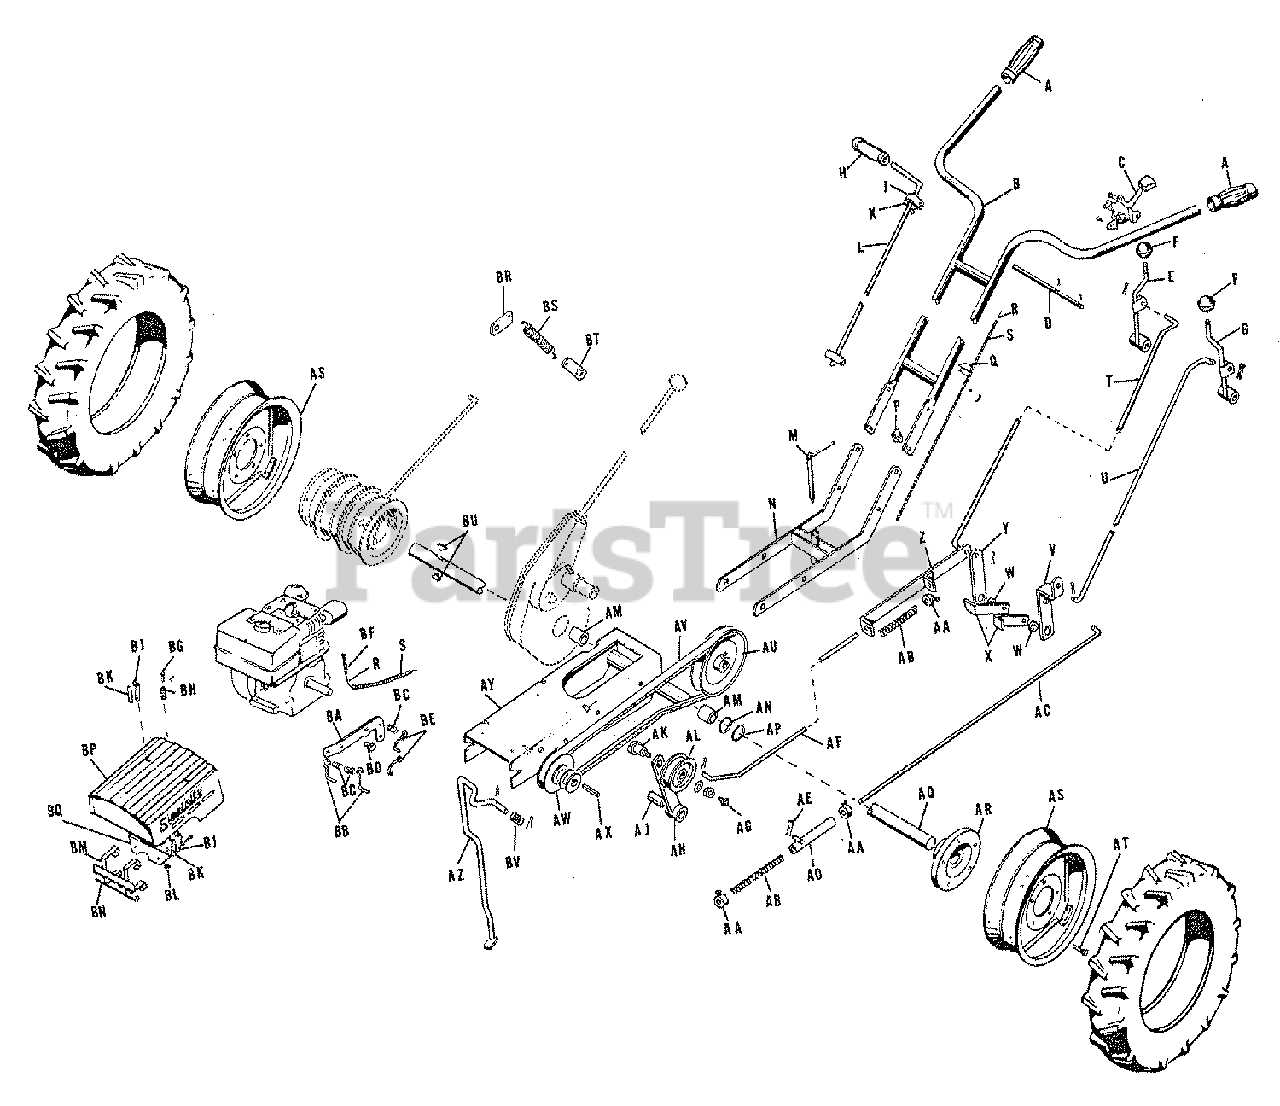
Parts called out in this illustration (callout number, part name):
A	GRIP, Handle
B	HANDLE ASSEMBLY
C	CONTROL, Throttle Lever
D	SHAFT, Lever
E	LEVER ASSEMBLY, R.H. Clutch
F	BALL, Clutch Lever
G	LEVER ASSEMBLY, L.H. Clutch
J	GUIDE, Rod
L	ROD ASSEMBLY, Shift
M	PIN ASSEMBLY, Hitch
N	FRAME ASSEMBLY
P	CLAMP, Cable
Q	CLIP, Cable
R	WIRE, Throttle
S	CABLE, Throttle
T	ROD, Upper Idler
U	ROD, Upper Clutch
V	LEVER, Lower Clutch
X	STOP, Lever
Y	LEVER, Pivot
Z	GUIDE ASSEMBLY, Idler Clutch Rod
AA	COLLAR, Set
AB	SPRING, Idler Rod
AC	ROD, Lower, Clutch
AD	SOCKET ASSEMBLY, Rod
AE	CLIP, Spring
AF	ROD, Lower Idler
AG	FITTING, Grease, Alemite #1911
AH	LEVER ASSEMBLY, Idler
AJ	SPACER, Idler Lever
AK	PIN, Idler Pulley
AL	PULLEY ASSEMBLY, Idler
AM	BEARING, Axle
AP	RING, Retaining
AR	HUB, Wheel, L.H.
AS	WHEEL (Specify Color)
AU	PULLEY, Transmission
AV	V" BELT, 46" Long`
AW	PULLEY, Engine
AX	KEY, Engine Pulley
AY	BASE ASSEMBLY
AZ	STAND ASSEMBLY
BA	HOLDER, Belt Stop
BB	STOP, Belt
BD	SCREW, Hex Head Cap, 5/16"-18 x 1/2"
BE	STOP, Belt
BF	SPRING, Throttle Wire
BG	PIN, Hood
BH	SPRING, Hood
BK	LATCH, Stub
BL	NUT, Hex, Full Lock 1/4"-20
BM	SUPPORT ASSEMBLY, Hood Pivot
BN	PIN, Hinge
BP	HOOD ASSEMBLY
BQ	BRACKET, Hood
BR	HOLDER, Spring, Upper
BT	HOLDER, Spring, Lower
BU	KEY, Hi-Pro, HP-608
BV	SPRING, Stand
